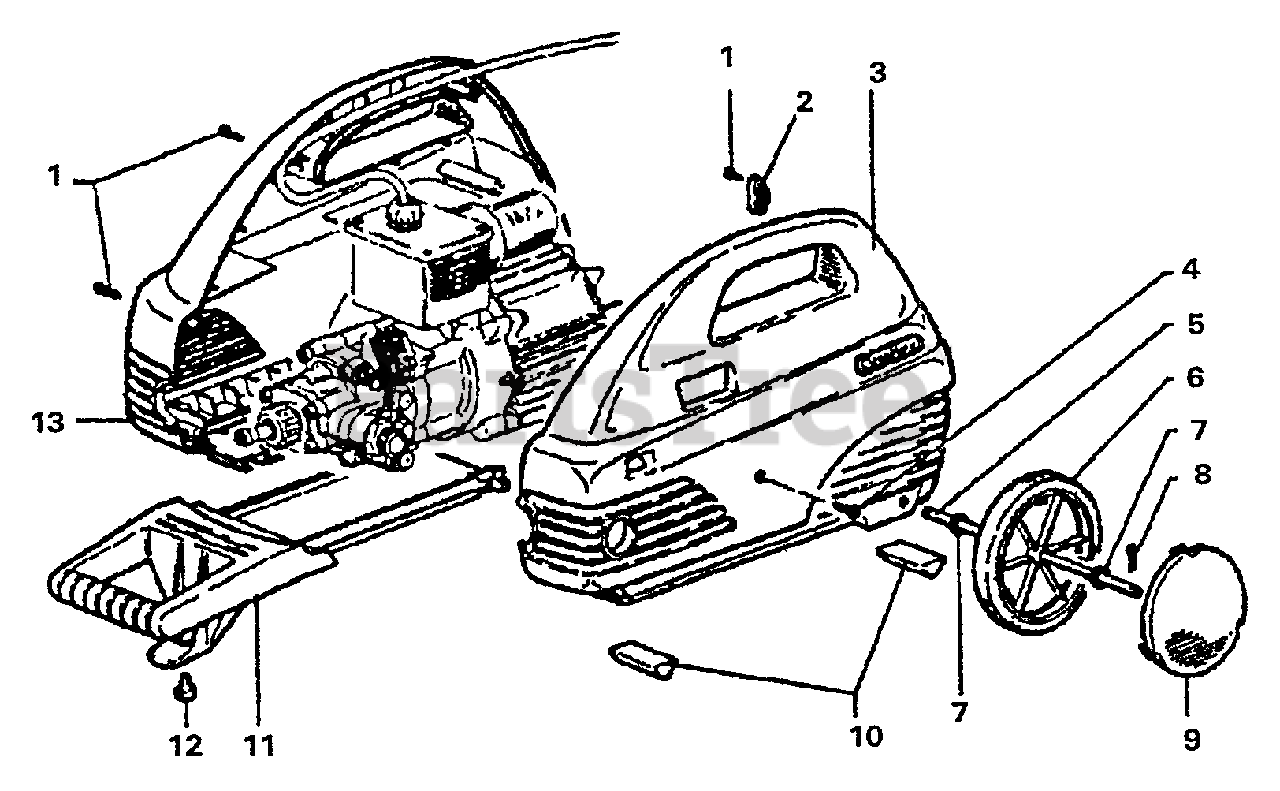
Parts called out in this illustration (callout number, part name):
1	SCREW - 4X18
2	COVER
3	COVER - LEFT
4	SCREW - 4X13
5	SHAFT
7	WASHER
8	PIN, SPLIT
9	CAP, WHEEL
10	FEET, PUMP
11	HANDLE
12	PLUG
13	COVER - RIGHT
